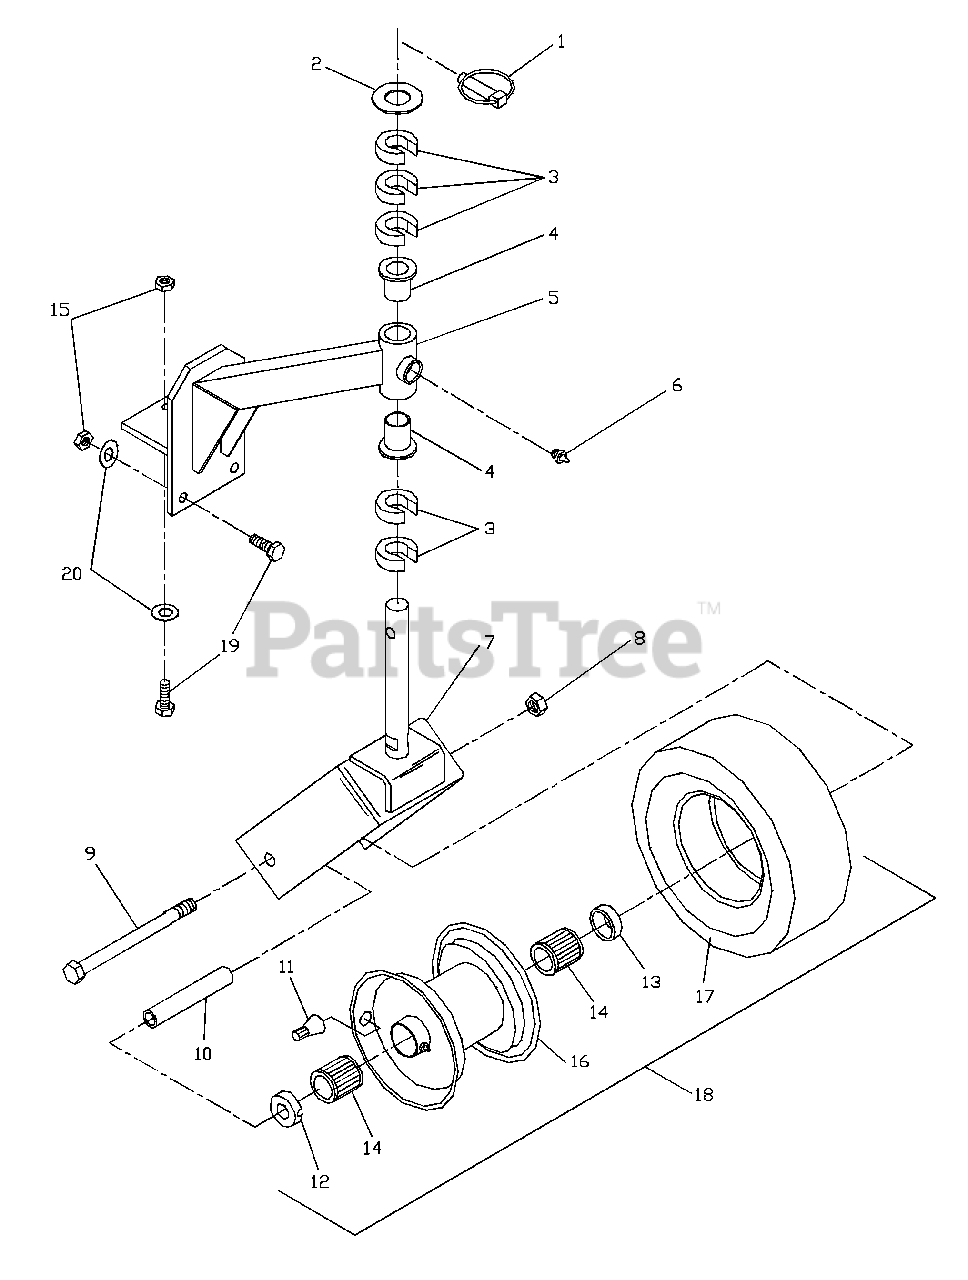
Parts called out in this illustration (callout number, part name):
1	7/16 LYNCH PIN
2	MACH. BUSHING
3	"C"-SPACER
4	FLANGE BUSHING
5	CASTER ARM W/BUSHING
6	ZERK 1/8 NPT
7	CASTER YOKE
8	1/2C NYLOC NUT
9	HCS 1/2C X 5 1/2
12	NOTCHED ENDCAP
13	ENDCAP
14	ROLLER BEARING
18	TIRE & WHEEL ASS.
19	HCS 3/8C X 1
20	FW 3/8 STD
21	FRONT WHEEL CASTER ASM. KIT
